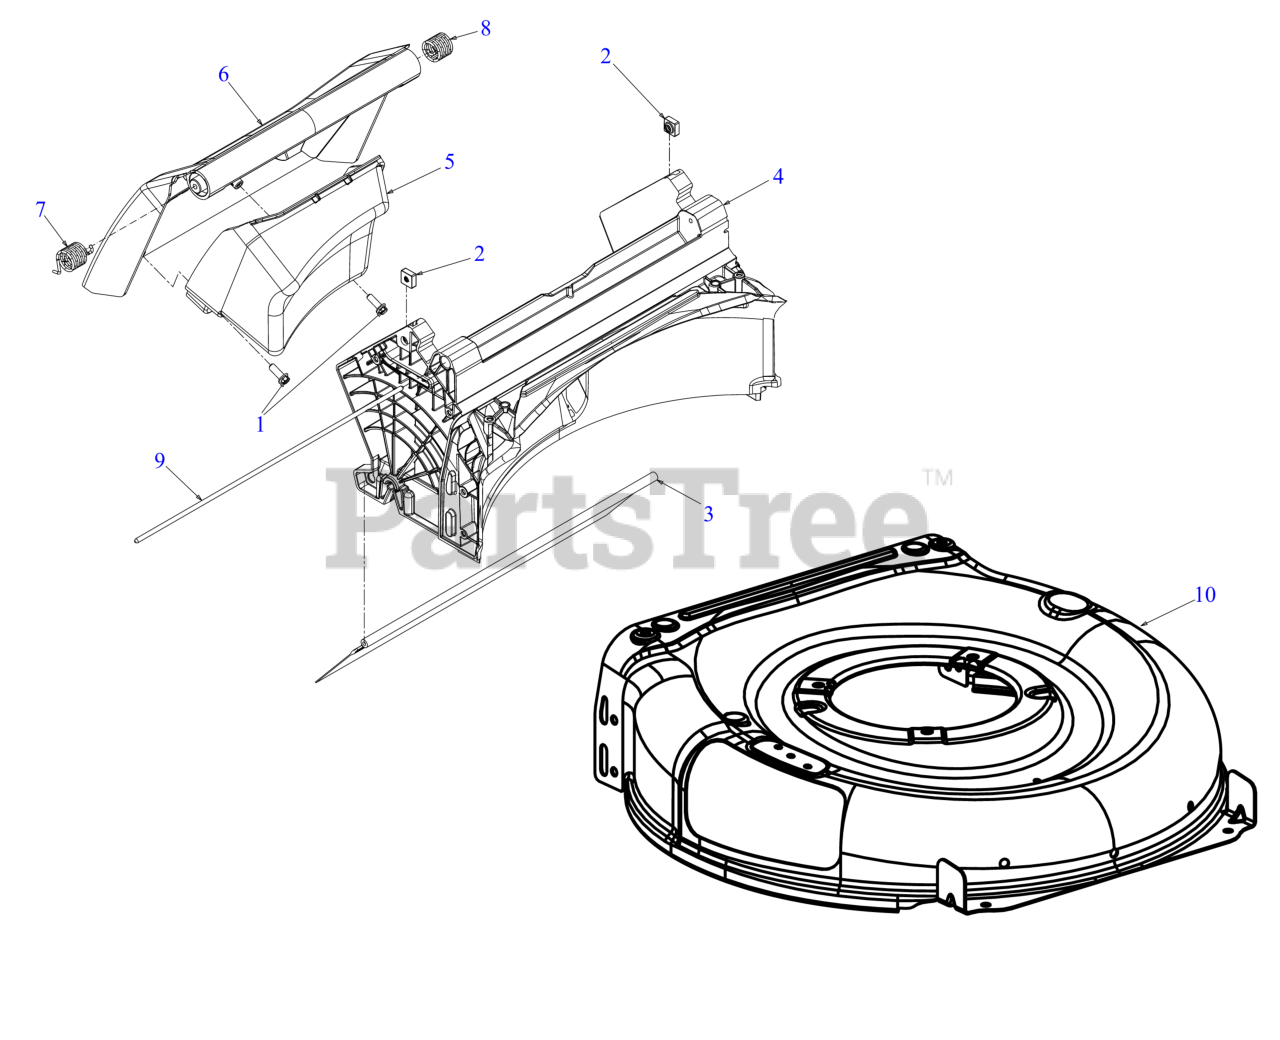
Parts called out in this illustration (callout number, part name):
1	SCREW 1/4 x .750
2	SQUARE LOCK NUT 1/4X20
3	TRAILSHIELD
4	REAR BAG BAFFLE
5	NOT SERVICEABLE
6	NOT SERVICEABLE
7	TORSION SPRING (RH)
8	TORSION SPRING (LH)
9	NOT SERVICEABLE
